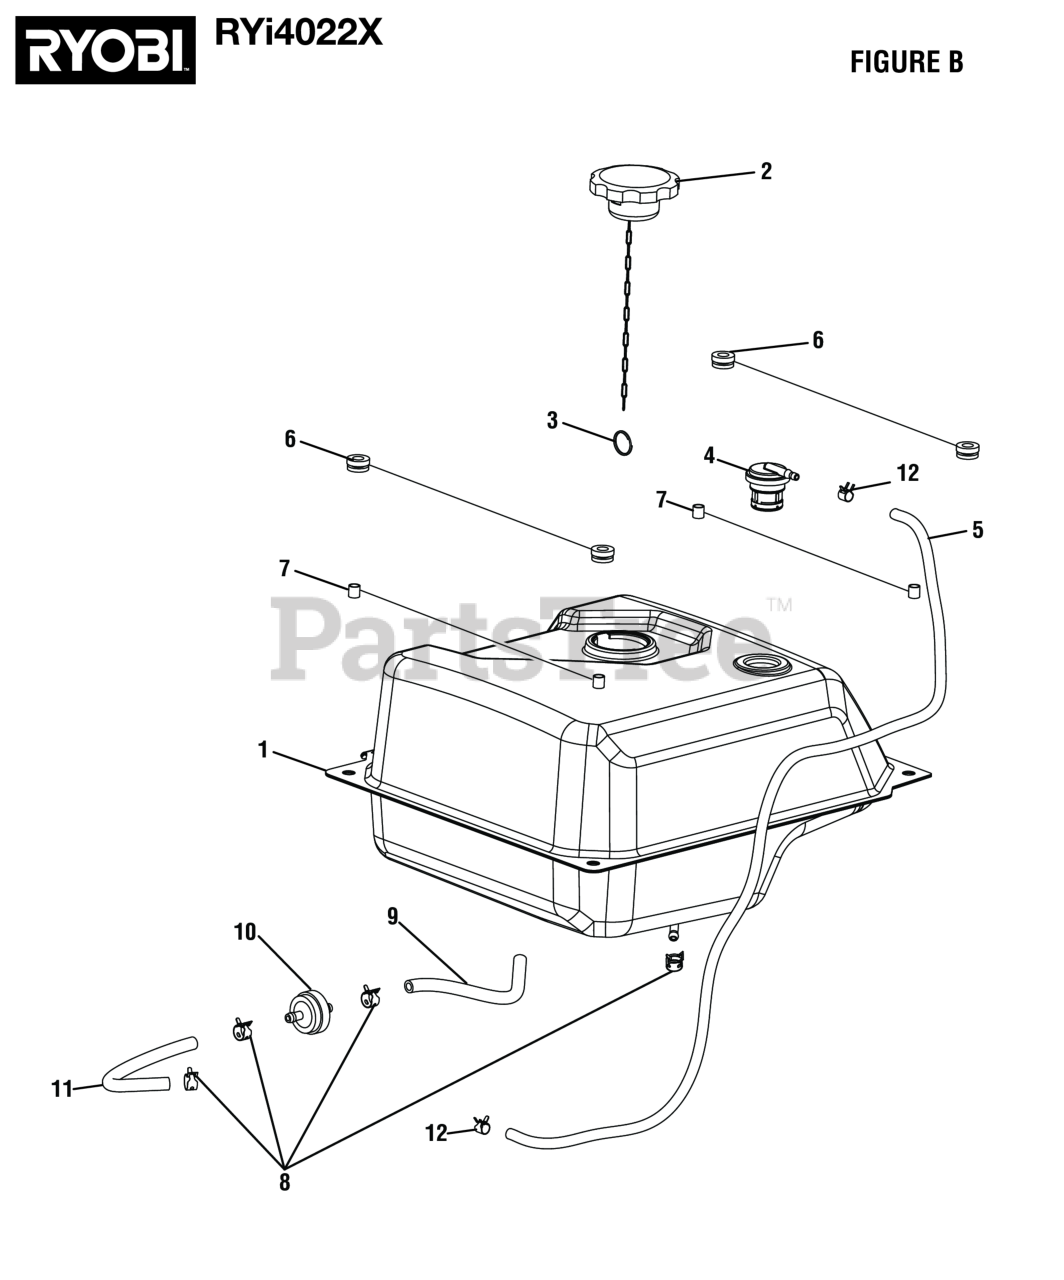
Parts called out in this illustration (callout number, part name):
1	Fuel Tank
2	Fuel Cap Assembly
3	Ring Clip
4	Fuel Tank Vapor Vent
5	Vapor Hose (4.5 mm x 760 mm)
6	Bushing (Fuel Tank Isolator)
7	Spacer (Fuel Tank Isolator)
8	Fuel Line Clamp (1/2 in.).
9	Fuel Hose (6.2 mm to 4.5 mm)
10	Fuel Filter Inline (1/4 in.)
11	Fuel Hose
12	Fuel Line Clamp (3/8 in.)
